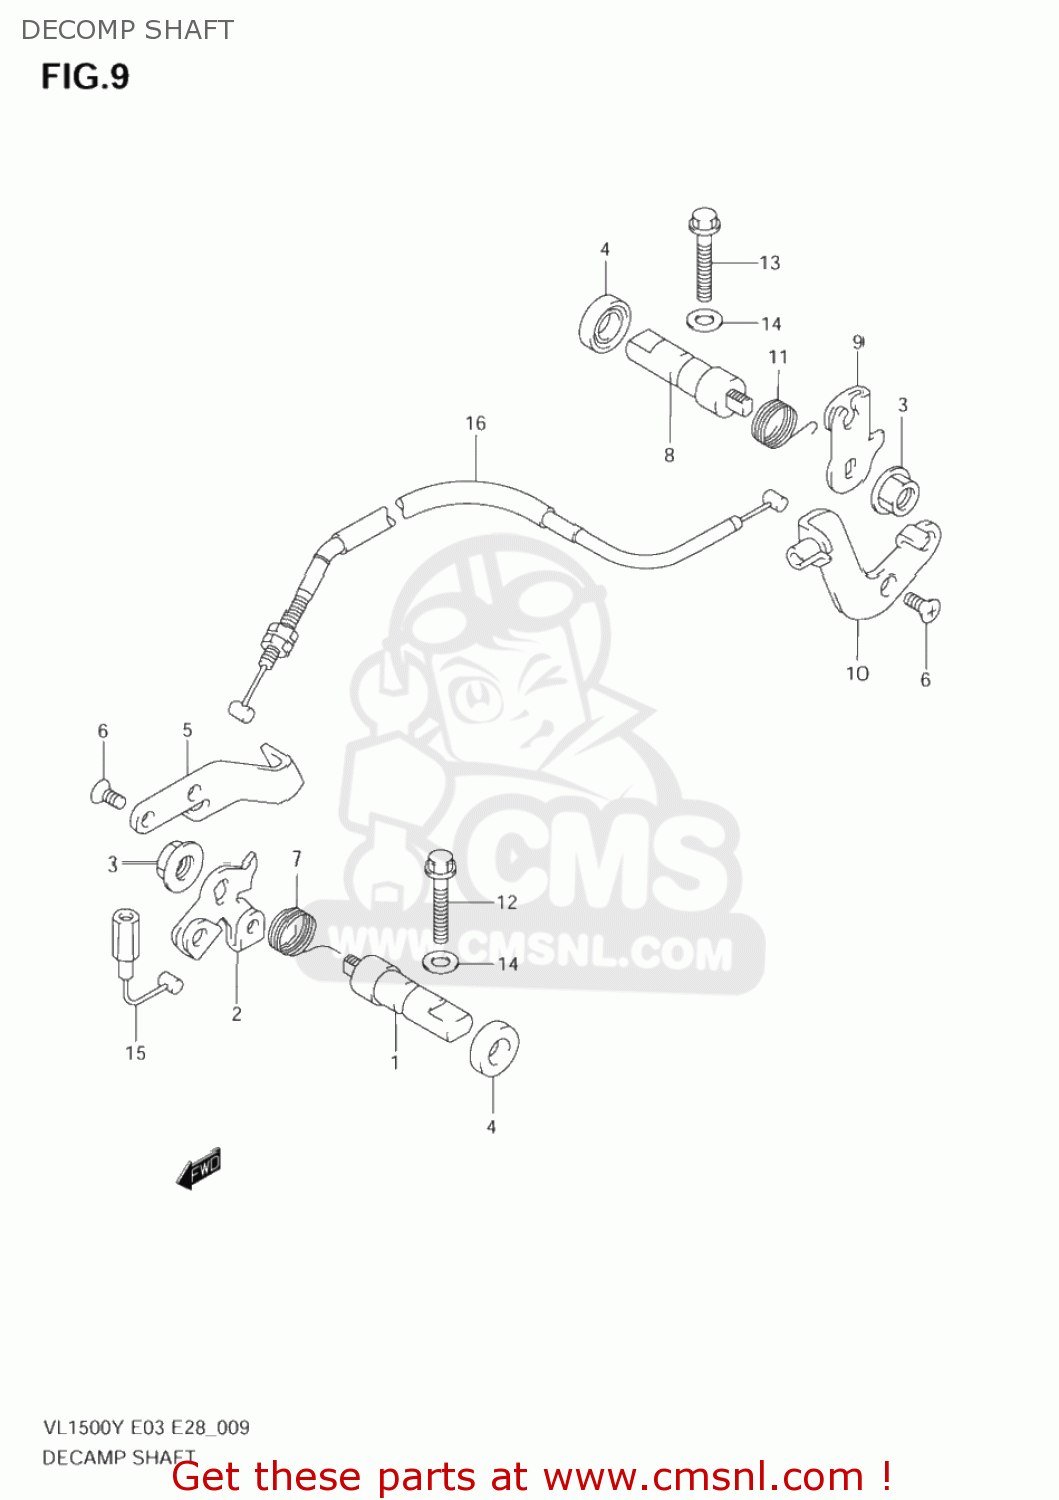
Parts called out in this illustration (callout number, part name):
1	SHAFT,DECOMP FR
2	LEVER,DECOMP SHAFT FR
3	NUT
4	SEAL,OIL(10X20X6)
5	HOLDER,DECOMP CABLE FR
6	SCREW
7	SPRING
8	SHAFT,DECOMP RR
9	LEVER,DECOMP SHAFT RR
10	HOLDER,DECOMP CABLE RR
11	SPRING
12	BOLT
13	BOLT
14	GASKET(5.8X13X1.2) (NAS)
15	CABLE ASSY,DECOMP FR
16	CABLE ASSEMBLY,DECOMPRESSION,REAR
